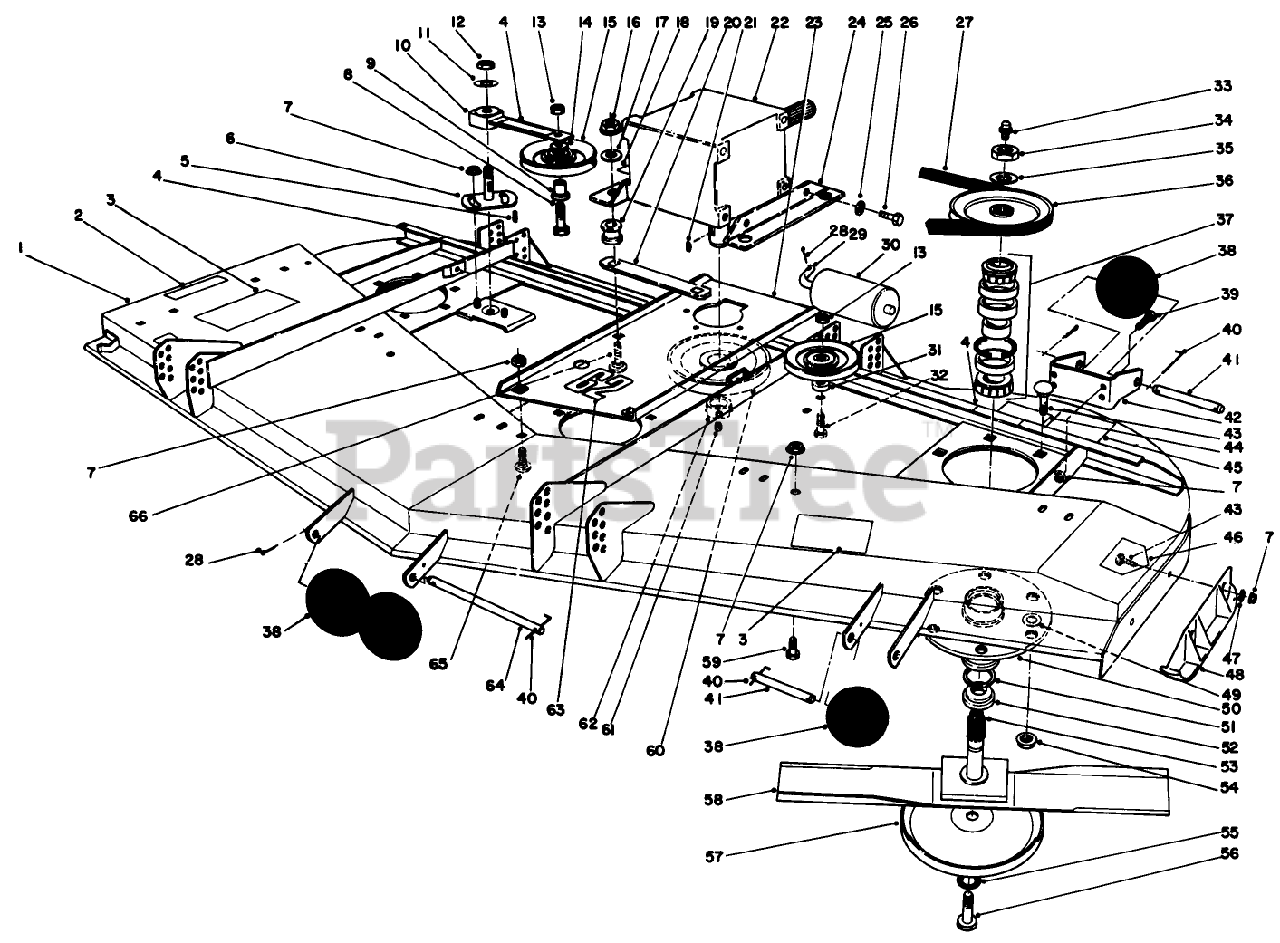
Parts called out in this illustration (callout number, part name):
1	Cutting Deck
2	DECAL-DANGER
3	DECAL-DANGER, THROWN OBJECT
4	DECAL-DANGER
5	KEY-SQUARE
6	PLATE-IDLER
7	NUT-HHF, WHIZ
8	SCREW-HH
9	BUSHING-PULLEY
10	IDLER ARM ASM
11	WASHER-FLAT
12	NUT-LOCK, NI
13	NUT-HEX
14	WASHER-FLAT
15	PULLEY-IDLER
16	NUT-LOCK, SIDE
17	WASHER
18	DECAL-OIL
19	MOUNT
20	Cover-Gear Box
21	KEY-WOODRUFF
22	Gearbox
23	Base-Gearbox
24	Bracket-Gearbox
25	WASHER-LOCK
26	SCREW-HH
27	V-BELT
28	PIN-COTTER
29	SHAFT-ROLLER, REAR
30	ROLLER-DECK
31	SPACER
32	SCREW-HH
33	FITTING-GREASE
34	NUT-HEX
35	WASHER
36	PULLEY AND HUB ASM
37	BEARING ASM
38	ROLLER
39	SCREW-HH
40	PIN-SPECIAL
41	SHAFT-ROLLER
42	Bracket-Roller
43	SCREW-CARR
44	DECAL-TORQUE
45	DECAL-WARNING
46	DECAL-DANGER
47	LOCKWASHER-PYRAMID
48	Skid
49	WASHER-FLAT
50	HOUSING-SPINDLE
51	SEAL-OIL
52	SPACER
53	SHAFT
54	NUT-HF
55	WASHER
56	SCREW-BLADE
57	CUP-SCALP, ANTI
58	Blade
59	SCREW-HH
60	PULLEY
61	SCREW-SET, HSH
62	Bushing-Taper Lock (Incl. Ref. #61)
63	DECAL
64	SHAFT-ROLLER
65	SCREW-CARR
66	SCREW-CARR
